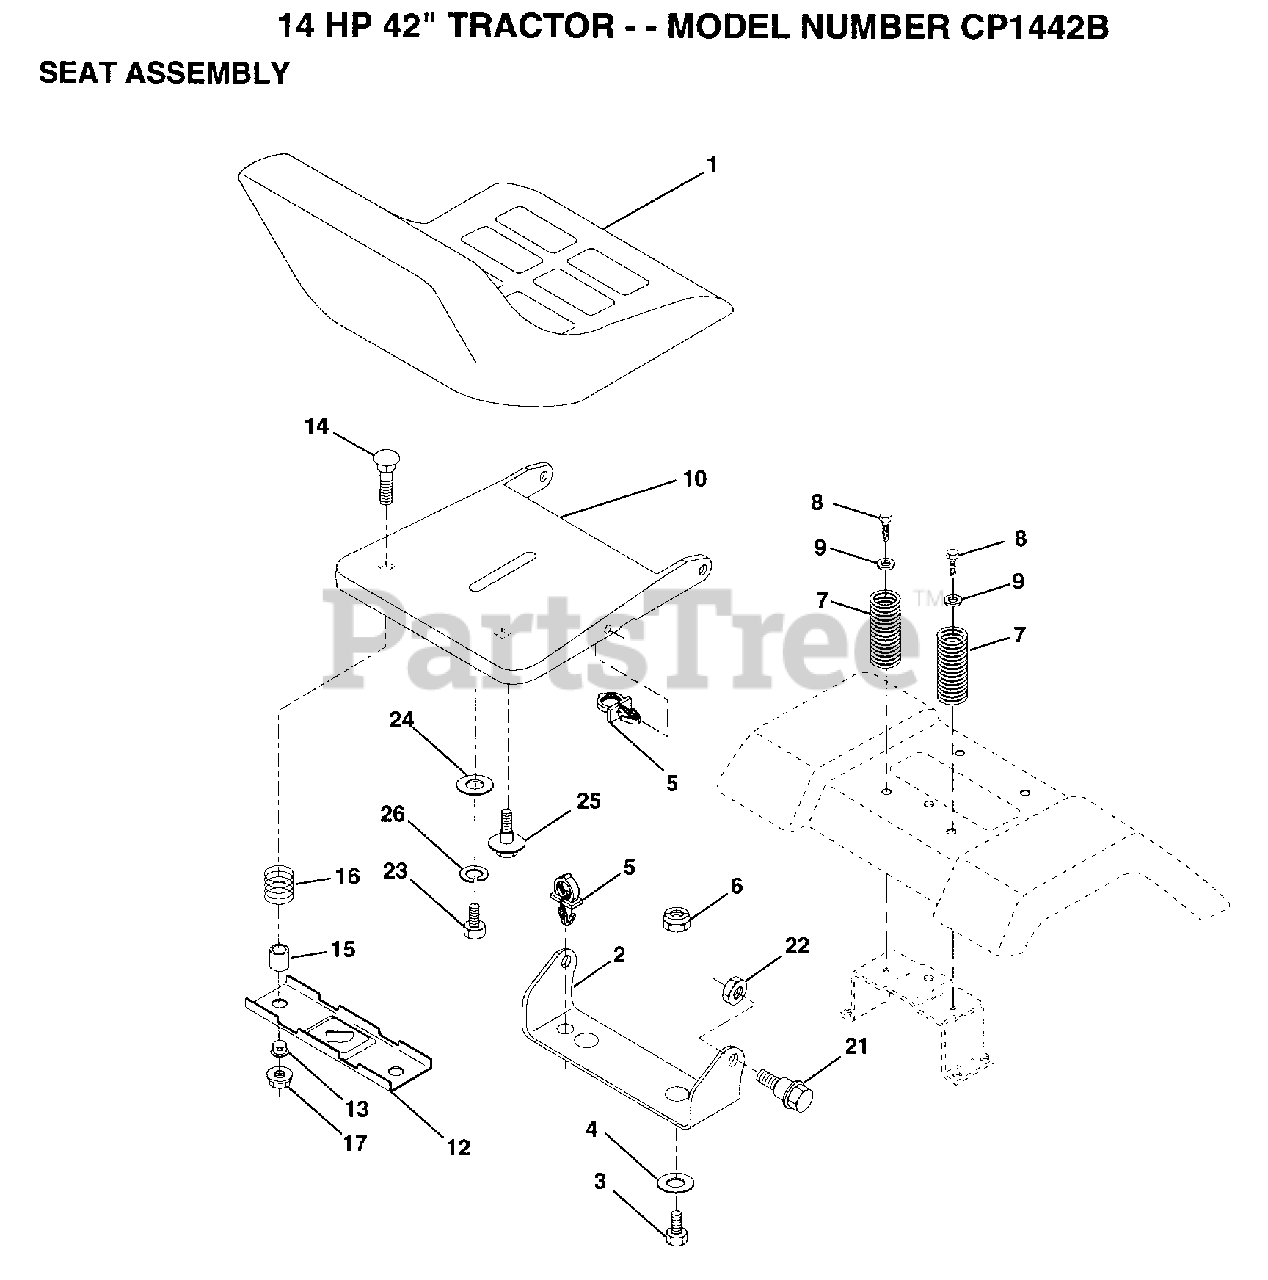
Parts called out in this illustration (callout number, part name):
2	BRACKET PVT SEAT
3	BOLT
4	WASHER PM
5	CLIP PUSH - IN
6	NUT
7	SPRING COMPRESSIO
8	SCREW GTV
9	WASHER
12	BRKT SWITCH
13	BUSHING
15	SPLIT SPACER
16	SPRING
21	BOLT.SHLD.5/16-18
22	NUT
23	BOLT
24	WASHER
25	"BOLT,SHOULDER"
26	LOCKWASHER
